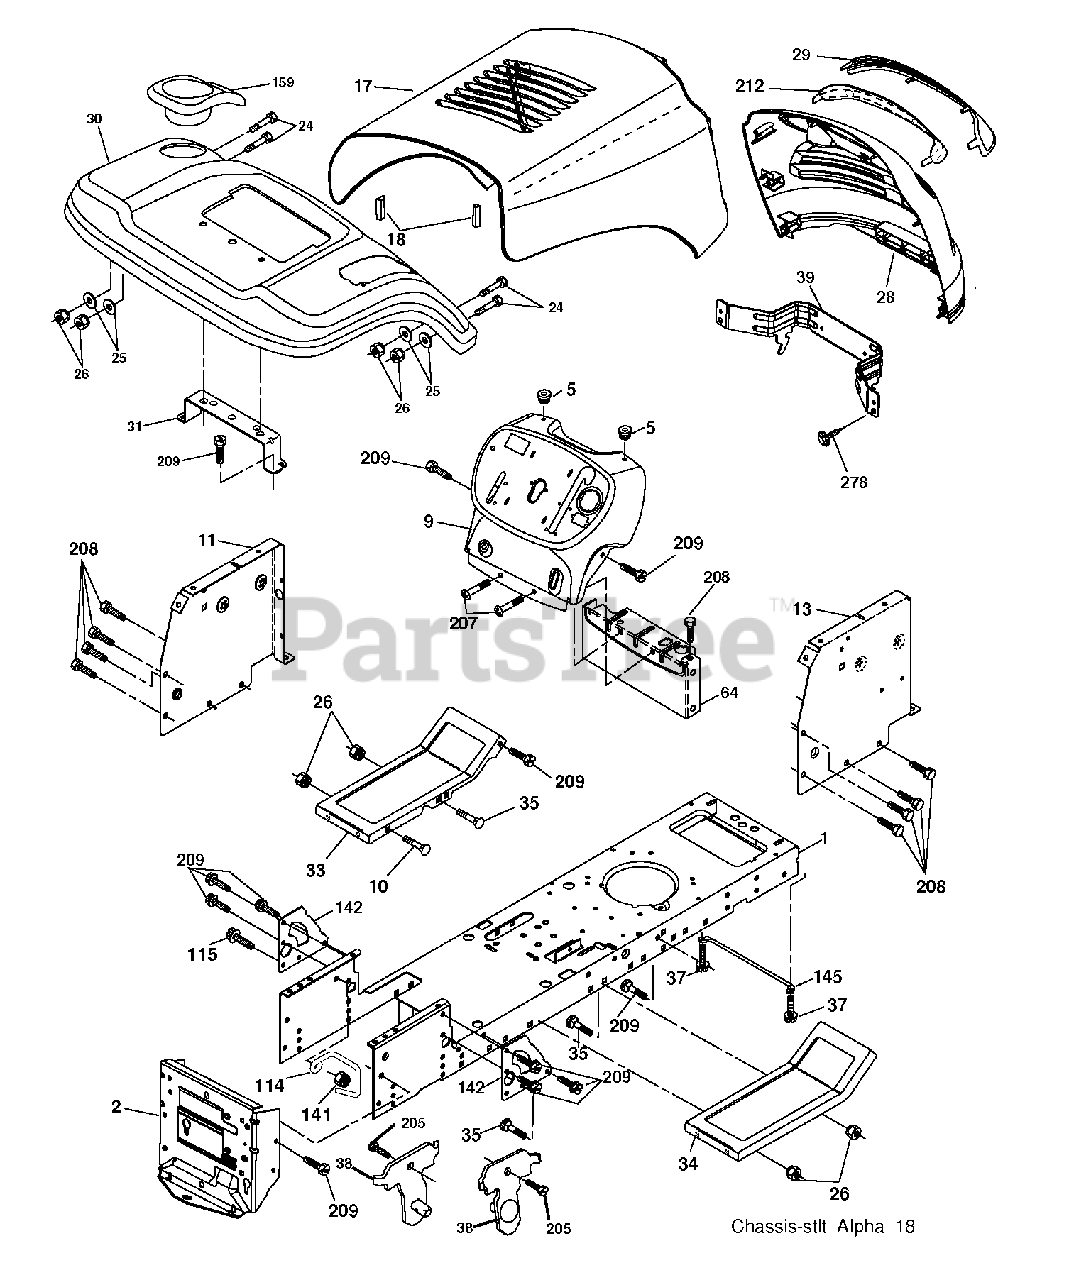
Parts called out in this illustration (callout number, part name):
1	CHASSIS STAMPING
2	DRAWBAR, 12GA
5	BUMPER.RUBBER.HOOD
11	PANEL.DASH.LH.LTX
17	HOOD.PNT.STEEL.ALPHA.LT.667
18	BUMPER.HOOD.LARGE.1.75"
25	WASHER
26	NUT
28	GRILLE.ASM.ALPHA
29	LENS.ALPHA.BAR.LT
30	FENDER.PNT.LIST.W/SFT.W/CUP.HD
31	BRACKET FENDER
33	FOOTREST.PNT.LH.MS667
34	FOOTREST.PNT.RH.MS667
37	SCREW LT
38	BRACKET.ASM.PIVOT.MOWER.REAR
39	BRACKET.PIVOT.ALPHA.LT
64	DASH LOWER
115	SCREW.3/8-16
141	NUT LOCK FLG 3/8-16 UNC
142	PLATE REINFORCEMENT
145	ROD.PIVOT.HOOD
159	CUPHOLDER.BLACK
205	SCREW LT
207	SCREW, 5/16-18 X 1/2
208	SCREW 3/8-16X1/2
209	SCREW, 3/8-16X3/4
212	INSERT.ALPHA.REFLECTIVE.LT.
278	SCREW.#10 X 0.750.BOS (2 2)
